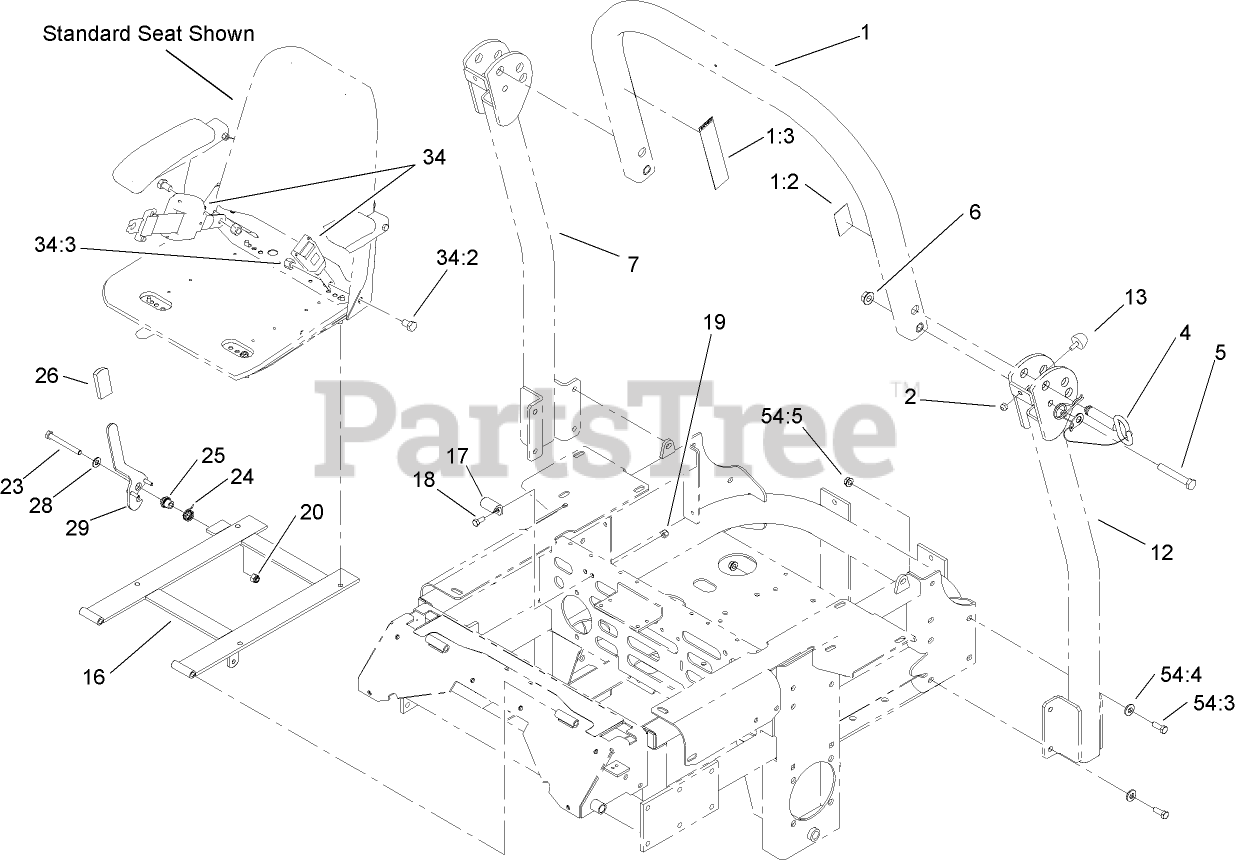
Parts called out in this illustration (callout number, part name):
1	Upper Tube ASM
1:2	DECAL-ROPS
1:3	DECAL-WARNING, FOLDING ROPS
2	NUT-LOCK, NI
4	PIN-FOLD, ROPS
5	SCREW-HH
6	NUT-HF
7	TUBE-SUPPORT, RH
12	TUBE-SUPPORT, LH
13	BUMPER-RUBBER
16	SEAT SUPPORT FRAME ASM
17	Catch-Latch, Seat
18	SCREW-HH
19	NUT-LOCK, NI
20	NUT-LOCK, NI
23	SCREW-HH
24	SPRING-TORSION
25	BUSHING-LATCH, SEAT
26	GRIP-LEVER
28	WASHER-FLAT
29	LATCH ASM
34	RETRACTABLE SEATBELT KIT
34:2	SCREW-HH
34:3	NUT-LOCK
54	BAG-BOLT, ROPS
54:3	SCREW-HH
54:4	WASHER-BELLEVILLE
54:5	NUT-HHF, WHIZ
